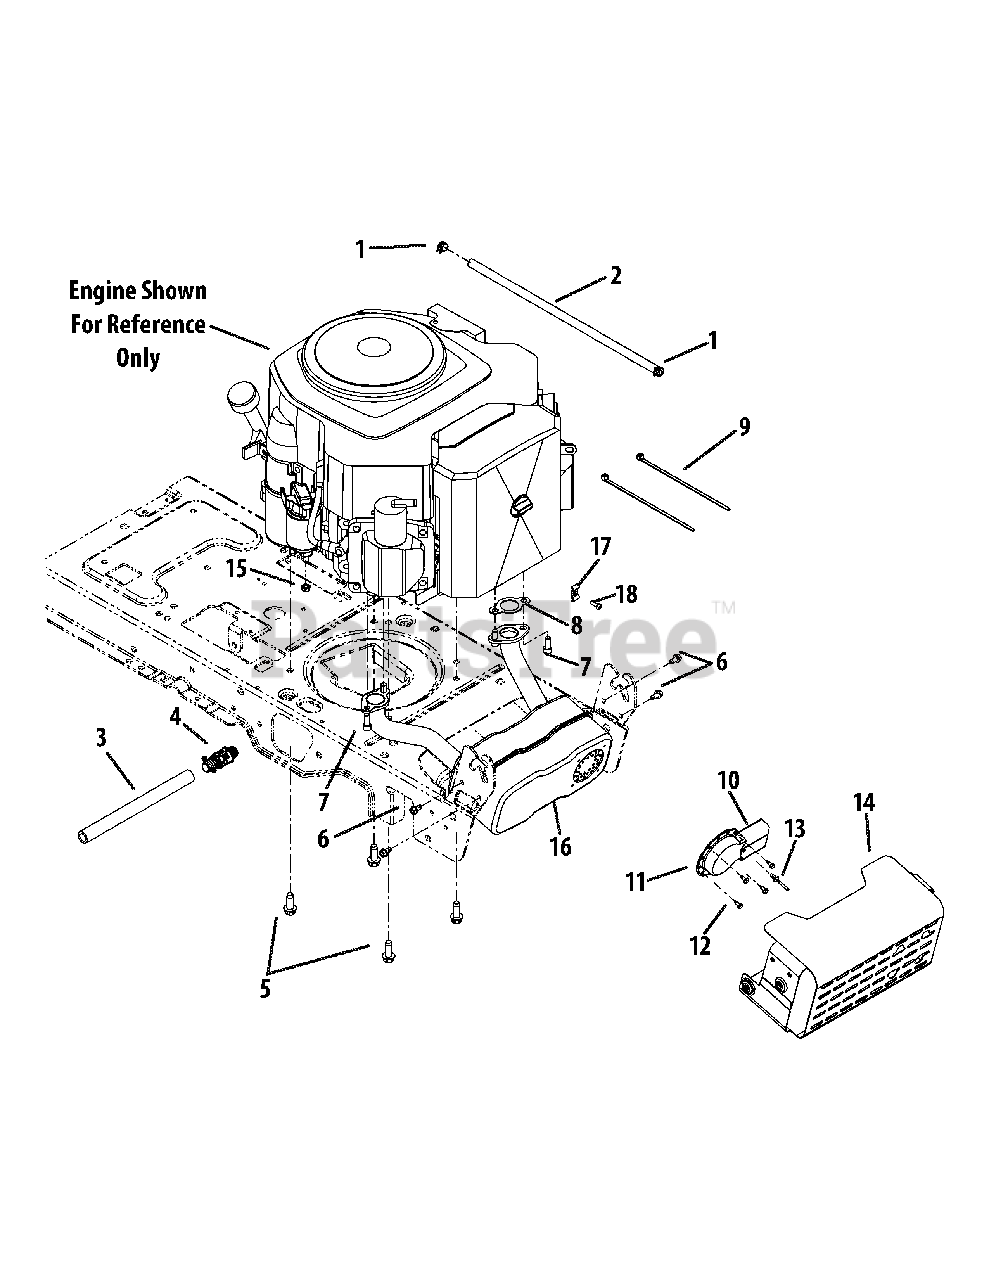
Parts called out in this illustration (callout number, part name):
1	Hose Clamp
3	Extension Hose
5	Hex Washer Screw, 3/8-16 x 1.00
6	Hex Washer Screw, 1/4-20 x .500
7	Screw, 5/16-18 x .750
8	Exhaust Gasket
9	Cable Tie, 3/16 x .05 x 7.4
10	Muffler Deflector
11	Long Muffler Deflector
12	Hex Washer Screw, #8-18 x .500
13	Rivet, .188 x .300
14	Muffler Shield Assembly
15	Sems Nut, 1/4-20
16	Kohler Twin Muffler
17	Dual Conduit Clamp
18	Tap Screw, M5 x .8
